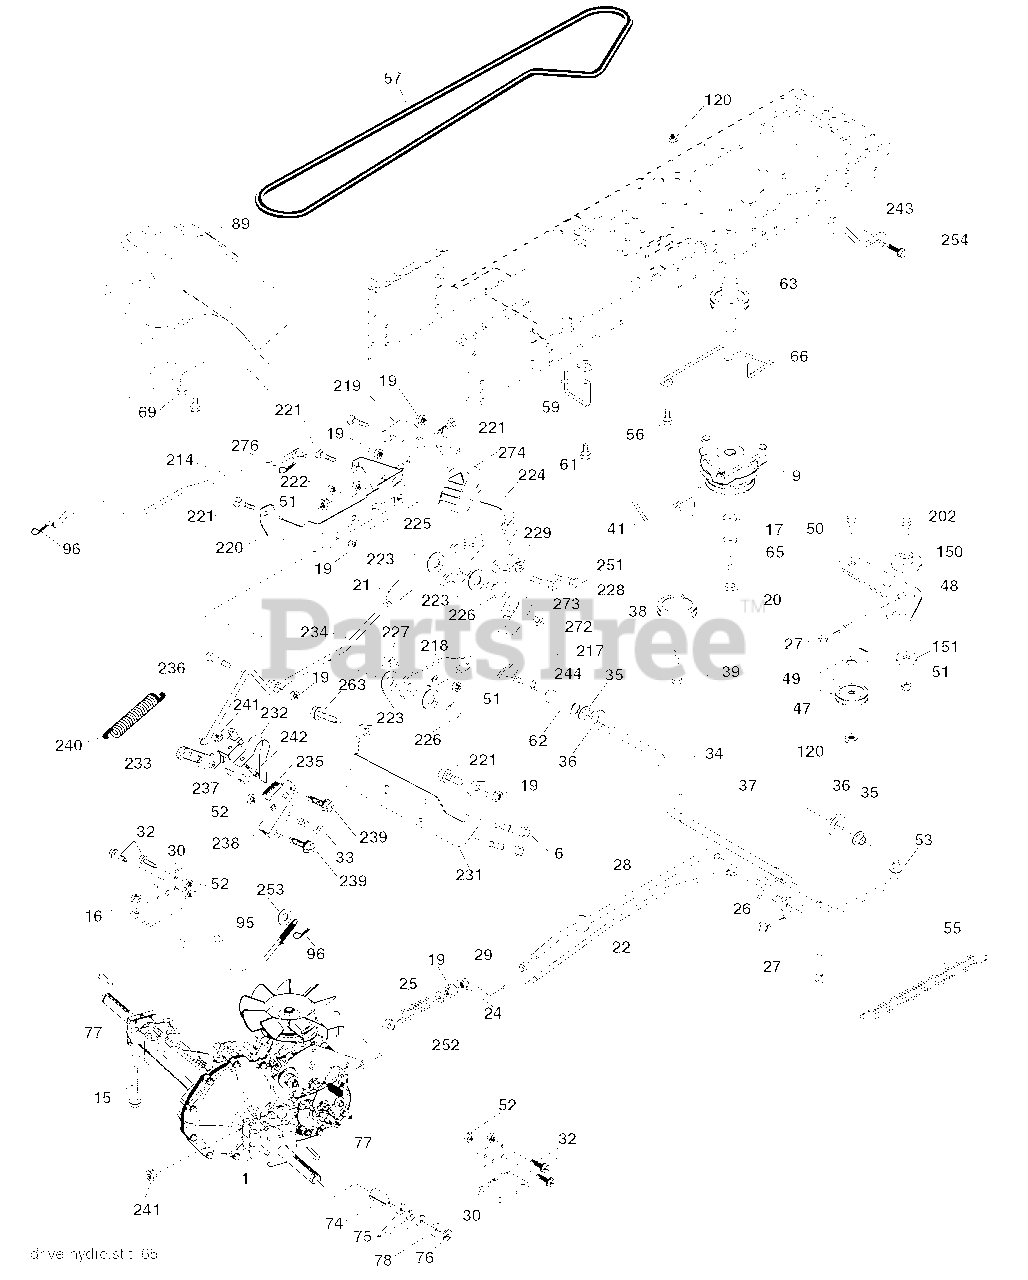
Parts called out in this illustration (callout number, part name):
1	Transaxle Hydro gear Model 347-0510 (See Breakdown)
6	Screw 5/16-18 x 3/4
9	Clutch Elec
15	Bolt Hex Flghd 5/16-18 Gr. 5
16	Nut Lock Hex W/Ins. 5/16-18 unc
17	Washer 1-1/2 OD x 15/32 ID x .250
19	Nut Lock Hex W/Wsh 3/8-16 unc
20	Bolt Hex 7/16-20 x 4 x Gr. 5-1.5
21	Knob Custom Control Cruise
22	Rod, Brake
24	Nut, Hex Jam 3/8-16 unc
25	Spring, Brake Rod
26	Washer
27	Pin Cotter 1/8 x 3/4 CAD.
28	Rod, Parking Brake
29	Cap Brake Parking
30	Bracket, Transaxle
32	Bolt Hex Hd 5/16-18 unc x 3/4
33	Bolt Rdhd Sqnk 5/16-18 unc x 3/4
34	Shaft, Foot Pedal
35	Bearing, Nylon
36	Washer
37	Pin, Roll
38	Pulley, Composite, Flat
39	Bolt Rdhd 3/8-16 unc x 2-3/4 Gr. 5
41	Keeper, Belt Idler Flat
47	Pulley, Idler, V-Groove
48	Bellcrank Clutch Grnd Drw Stl
49	Retainer, Belt
50	Bolt Carr Sh 3/8-16 x 1-1/2 Gr. 5
51	Nut Crownlock 3/8-16 unc
52	Nut, Crownlock 5/16-18 unc
53	Link, Clutch
55	Spring, Return, Clutch
56	Screw 3/8-16 x 1-1/4
57	V-Belt, Ground Drive
59	Keeper, Center Span
61	Screw 3/8-16 x .875
62	Cover, Pedal
63	Pulley, Engine
65	Washer
66	Keeper Belt Engine
69	Screw Hex Wsh Hi-Lo 1/4-1/2 unc
74	Spacer, Axle
75	Washer 25/32 x 1-1/4 x 16 Ga.
76	E-Ring
77	Key, Square
78	Washer 25/32 x 1-5/8 x 16 Ga.
89	Console, Shift
95	Rod Bypass
96	Retainer Spring 1" Zinc/Cad
120	Nut Lock Flg 3/8-16 unc
150	Spacer Retainer
151	Washer 13/32 x 2 x 10 Ga.
202	Bolt RDHD 3/8-16 unc x 1-3/4 Gr. 5
214	Link Transaxle
217	Pedal Reverse
218	Arm Control Pedal Reverse
219	Bracket Frest Pdl Ctrl. Hyd
220	Bracket Mtg. Pedal Control
221	Bolt Rdhd Sqnk 3/8-16 unc x 3/4
222	Nut Crownlock 7/16-14 unc
223	Washer Nylon 11/16 ID x .060
224	Pedal Forward
225	Arm Control Pedal Forward
226	Bolt Pivot Spacer
227	Cam Reverse Pedal LT
228	Bolt Shoulder 5/16-18
229	Washer Serrated 5/16 x .75
231	Strap Torque
232	Actuator Cruise Disengage
233	Pawl Control Cruise
234	Lever Control Cruise
235	Sector Control Cruise
236	Bolt Shoulder 3/8-16 unc 1/44
237	Bolt Shoulder 5/16-18
238	Arm Mtg. Cruise Sector
239	Screw Thdrol 5/16 x 1/2
240	Spring Return Cruise Control
241	Nut Centerlock 1/4-20 unc
242	Bolt Fin Hex 1/4-20 x .75
243	Bracket Anti-Rotation
244	Screw 5/16-18 x 5/8
251	Screw 5/16-18
252	Washer 13/32 x 1 x 16 Ga.
253	Washer .3125 x .615 x 16 Gr.
254	Screw 3/8-16 x 1
263	Screw 3/8-16 x .75
272	Screw, 5/16-18 x 1/2 TT
273	Pad, Reverse Pedal
274	Cover Pedal Forward
276	Clip Retainer .0375
